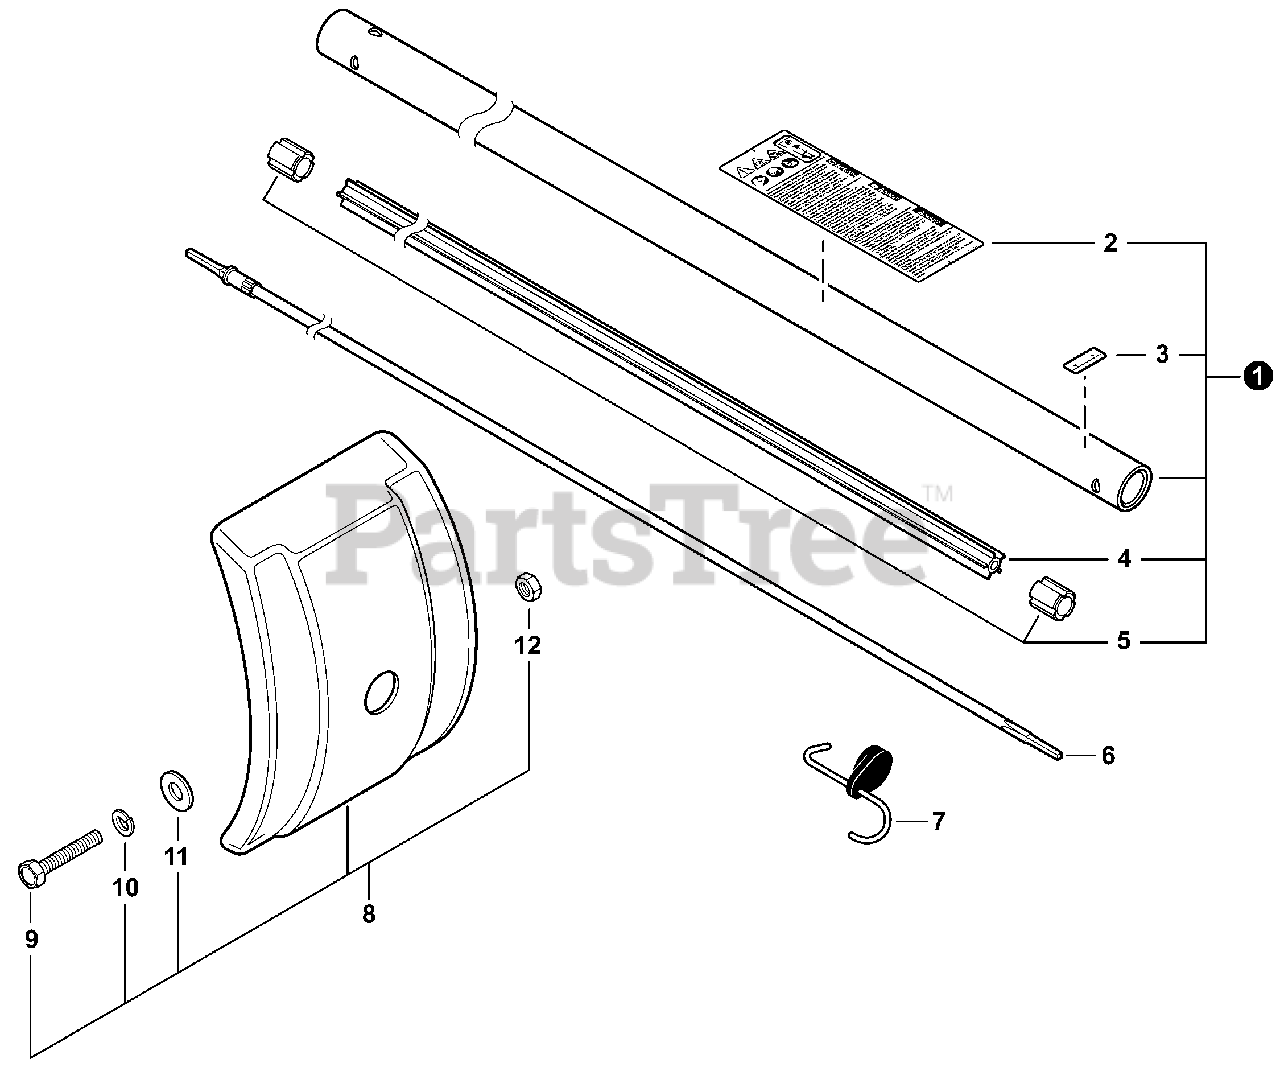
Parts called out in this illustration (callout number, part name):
1	MAIN PIPE ASSY
2	LABEL, CAUTION
3	LABEL - ALIGNMENT
4	LINER - FLEXIBLE
6	DRIVESHAFT - FLEXIBLE
7	HANGER, ATTACHMENT
8	DEBRIS SHIELD KIT
9	BOLT 6×20
10	WASHER, SPRING 6
11	WASHER 6.5×11.5×0.8
12	NUT, HEX M6
